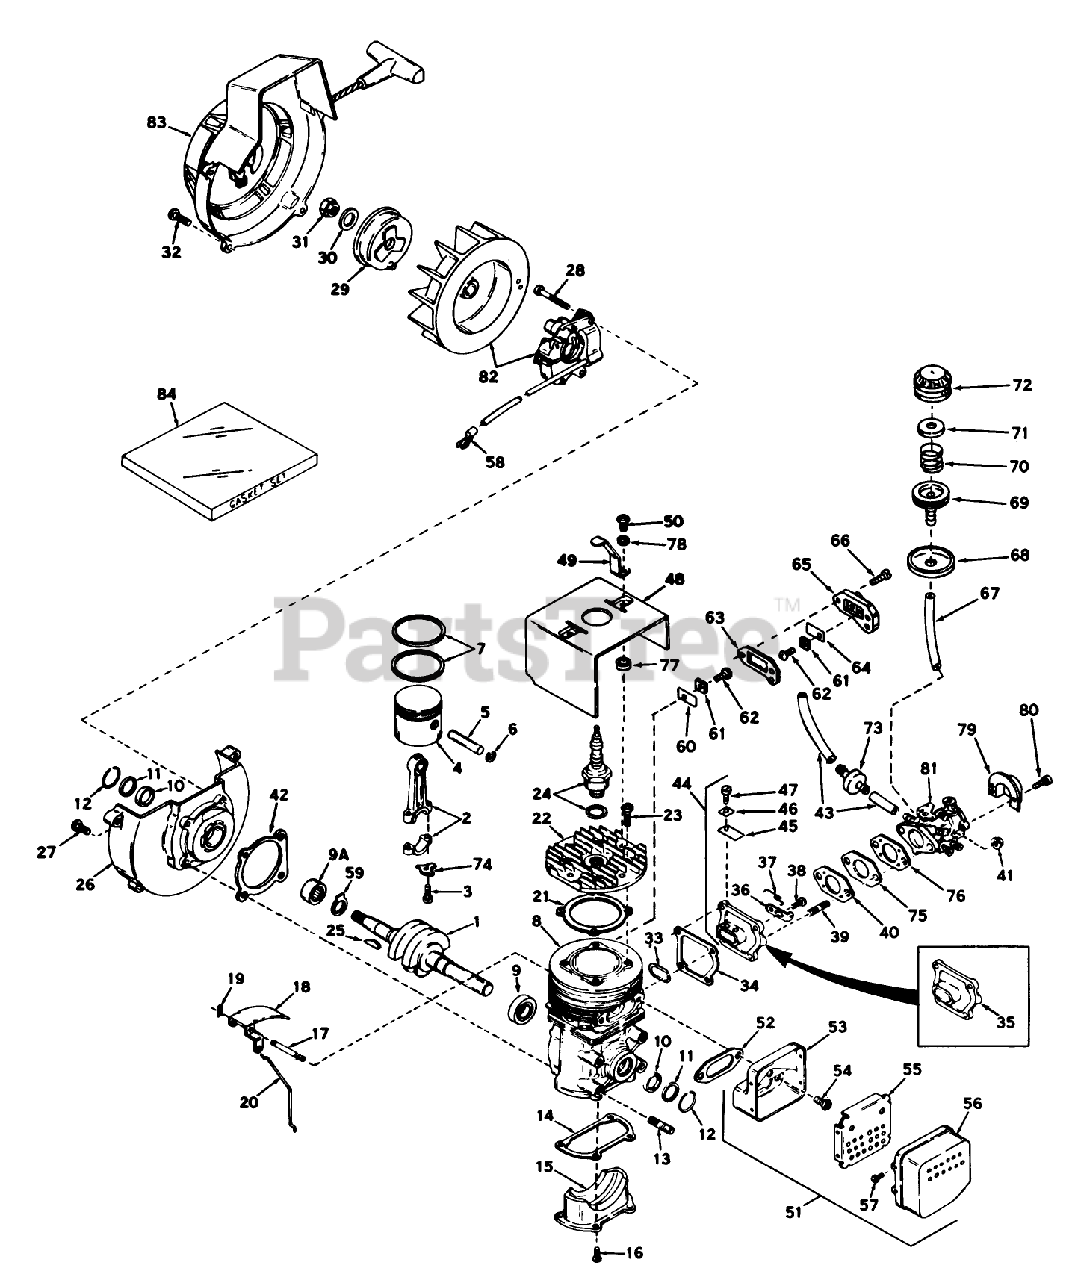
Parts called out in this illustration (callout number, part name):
1	Crankshaft
2	Rod Assy., Connecting(Incl. Nos. 3 & 74)
3	Bolt-Rod, Connecting
4	Piston
5	Pin, Piston
6	Ring, Piston Pin Retaining
7	Ring Set, Piston
8	Block Assy., Cylinder (Incl. Nos. 9, 10 thru 13 & 17)
9	Bearing Ball
9A	Bearing-Cartridge
10	Seal, Crankshaft
11	Retainer, Crankshaft Seal
12	Spring, Crankshaft Seal
14	Cover-Rubber
15	Plate, Cover
16	Screw (T-25, 10-24 x 1/2)
17	Shaft, Air Vane
18	Vane Assy, Air
19	Clip,Air Vane
20	Link Governor
21	Gasket, Cylinder Head
22	Screw
23	Screw (T-30, 1/4-20 x 3/4)
24	Plug, Spark (AC-47M)
25	Key, Woodruff
26	Base Assy., Shroud (Incl. Nos. 9A thru 12)
27	Screw
29	Cup, Starter
30	Washer, Flat
31	Nut, Flywheel
32	Screw (T-30, 1/4-20 x 3/4)
33	Gasket, Port
34	Gasket, Adapter Cover
35	Cover, Adapter Type 1401C
36	Lever, Adjusting
37	Spring, Adjusting Lever
38	Screw
40	Gasket, Carburetor 1/8" thick)
41	Locknut
42	Gasket, Shroud Base
43	Line-Fuel (8.62)
44	Plate Assy., Reed (Incl. Nos. 45, 46 & 47) Type 1450B
45	Reed Type 1450B
46	Stop, Reed Type 1450B
47	Screw, Pan Flex Hd. type 1450B
48	Shroud, Cylinder
49	Lever, Stop
50	Screw
51	Muffler Assy.
52	Gasket-Muffler
53	Base, Muffler
54	Screw
55	Baffle Muffler
56	Cover Muffler
58	Screw
59	Washer, Thrust
60	Reed, Compression Release
61	Plate, Reed Hold Down
63	Gasket, Compression Release
64	Reed, Compression Release
65	Cover, Compression Release
66	Screw
67	Beam Assy.
68	Retainer, Primer Bulb
69	Body Primer
70	Spring, Primer Bulb
71	Washer, Primer Bulb
72	Bulb, Primer
73	Filter, Fuel
74	Washer, Tab
75	Spacer
76	Gasket, Carburetor (1/16"thick)
79	Baffle-Carburetor
81	Carburetor
82	BRACKET S
83	Shroud & Starter Assy.
84	Gasket Set
